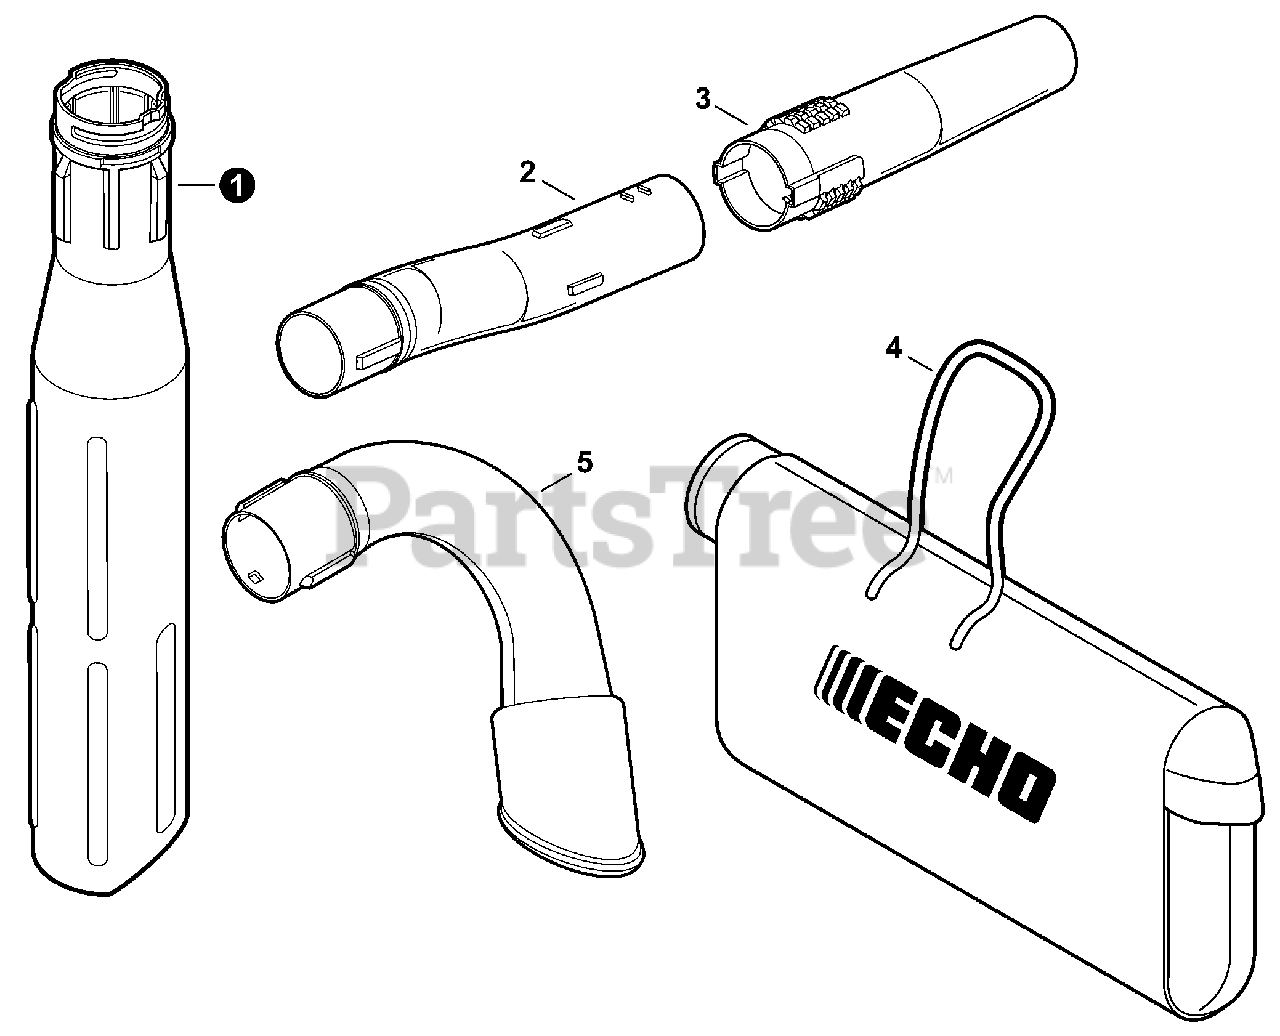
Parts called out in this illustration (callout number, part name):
1	TUBE, BLOWER - SUCTION
2	TUBE, BLOWER - CURVED
3	TUBE, BLOWER - ROUND NOZZLE
4	BAG, DEBRIS
5	TUBE, BLOWER - ELBOW
